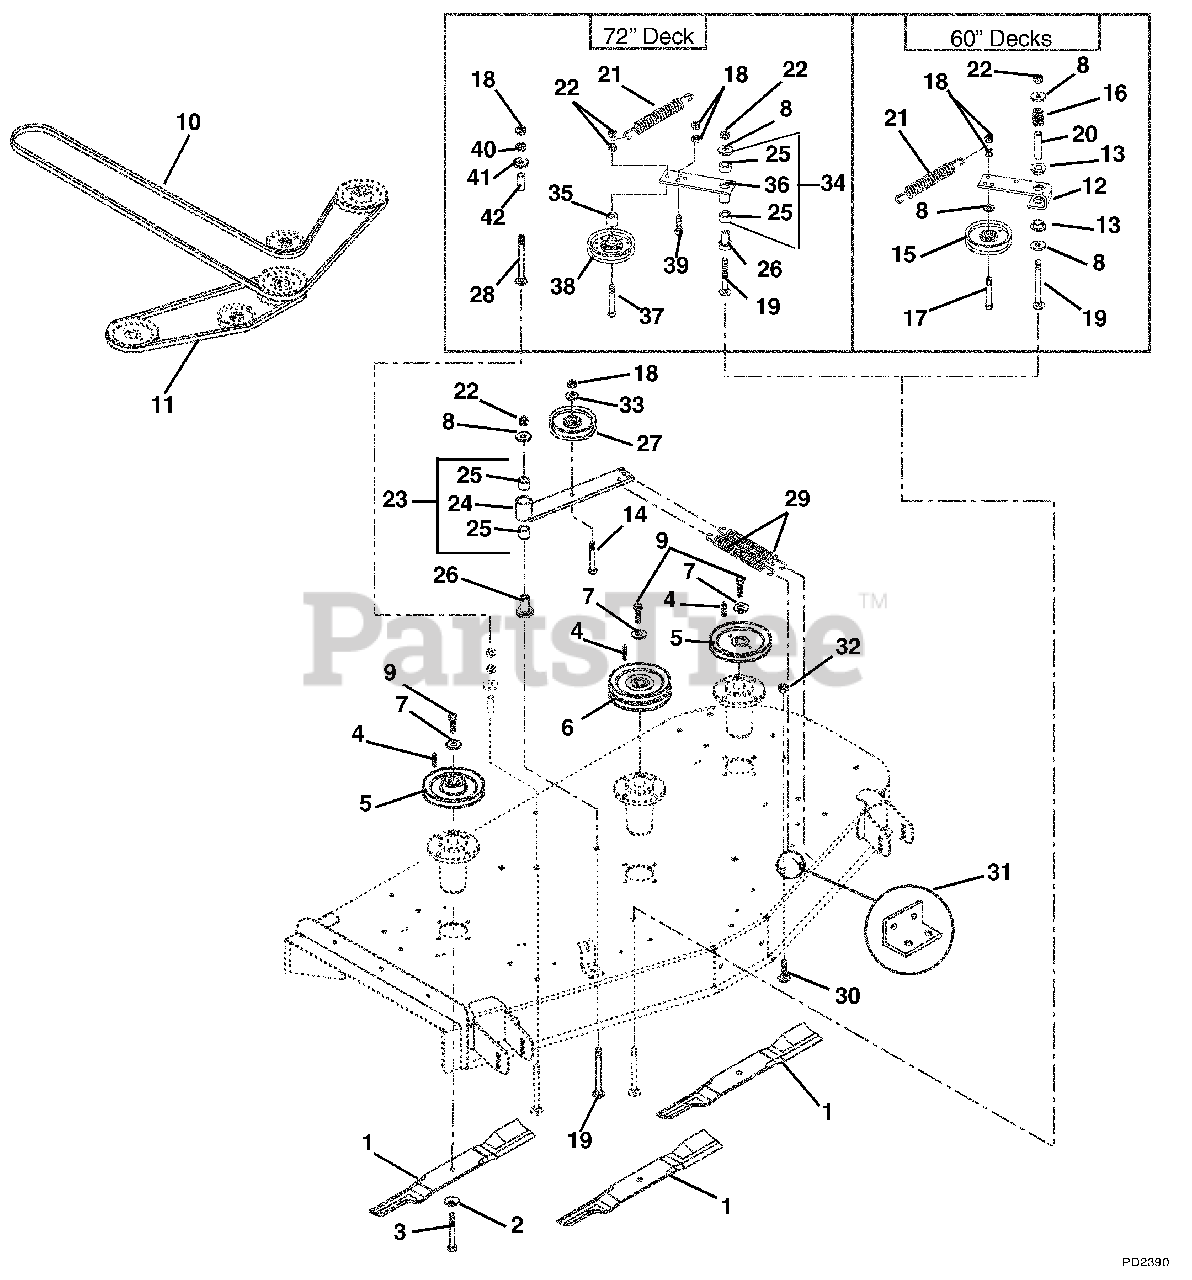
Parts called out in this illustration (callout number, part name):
1	Blade, Mower-72" Without Tungsten Carbide Hardfacing (036, 038, 039)
1	Blade, 60" Mower (036, 038, 039)
1	Blade, 60" Mulching Tungsten (036, 038, 039)
1	Blade, 72" Mulching Tungsten (036, 038, 039)
1	Blade 60" Mower CE (309)
2	Washer-Bellville .63 x 1.625 x .14
3	Bolt-Hex .62-18 x 1.75 Grade 8
4	Key-Straight .25 x 1.00 x .25
5	Weldment, Spindle Sheave 7.00 (037, 039)
5	Weldment, Spindle Sheave 6.00 (036, 038, 309)
6	Weldment, Sheave (Double) 7.25 (037, 039)
6	Weldment, Spindle Sheave (Double) 6.25 (036, 038, 309)
7	Washer, Cupped, Serrated .375
8	Washer-Flat-Steel .531 x 1.25 x .100 (037, 039)
8	Washer-Flat-Steel .531 x 1.25 x .100 (036, 038, 309)
9	Bolt-Hex .38-16 x 1.00 Grade 8
10	V-Belt, B-RMA 69.81 x .625 (037, 039)
10	V-Belt, B-RMA 63.40 x .625 (036, 038, 309)
11	V-Belt, B-RMA 28.62 x .625 (037, 039)
11	V-Belt, B-RMA 23.94 x .625 (036, 038, 309)
12	Arm, Idler Pivot (036, 038, 309)
13	Bushing-Flange-Nylon .762 x 1.0 x .58 x 1.48 (036, 038, 309)
14	Bolt, Hex .38-16 x 3.00 Grade 5
15	Idler-V 4.00 x .377 (036, 038, 309)
16	Spring-Compression .085 x .80 x 1.00 (036, 038, 309)
17	Bolt-Hex .38-16 x 2.25 Grade 5 (036, 038, 309)
18	Nut-Locking-Center .38-16 (036, 038, 309)
18	Nut-Locking-Center .38-16 (037, 039)
19	Bolt-Round Head Square Neck .50-13 x 3.50
20	Spacer .560 x .750 x 2.437 Steel (036, 038, 309)
21	Spring, Extension
22	Nut-Locking-Center .50-13 (037, 039)
22	Nut-Locking-Center .50-13 (036, 038, 309)
23	Assembly, Idler Pivot Arm
24	Weldment, Idler Pivot Arm
25	Bearing, 1.00 x 1.12 x .75
26	Bearing, Pedistal Powdered Metal (037, 039)
26	Bearing, Pedistal Powdered Metal (036, 038, 309)
27	Idler-Flat 4.00 x .38 (2.00 W)
28	Bolt-Round Head Square Neck .38-16 x 2.75 Grade 5
29	Spring, Extension
30	Bolt-Round Head Square Neck .38-16 x 1.00 Grade 5
31	Bracket, Spring (036, 037)
31	Bracket, Spring (038, 039, 309)
32	Nut-Locking-Nylon .38-16
33	Washer-Flat-Steel .375 x 1.125 x .065
34	Assembly, Idler Arm-Ground Drive
35	Spacer .51 x .75 x .62 (037, 039)
36	Weldment, Idler Arm Ground Drive (037, 039)
37	Bolt-Hex .50-13 x 2.50 Grade 5 (037, 039)
38	Idler-Flat-Pulley 6.75 x .510 (037, 039)
39	Bolt-Hex .38-16 x 1.25 Grade 5 (037, 039)
40	Nut-Locking-Nylon .38-16 (037, 039)
41	Washer-Flat-Steel .406 x .812 x .065 (037, 039)
42	Spacer .380 x .625 x 1.50 (037, 039)
